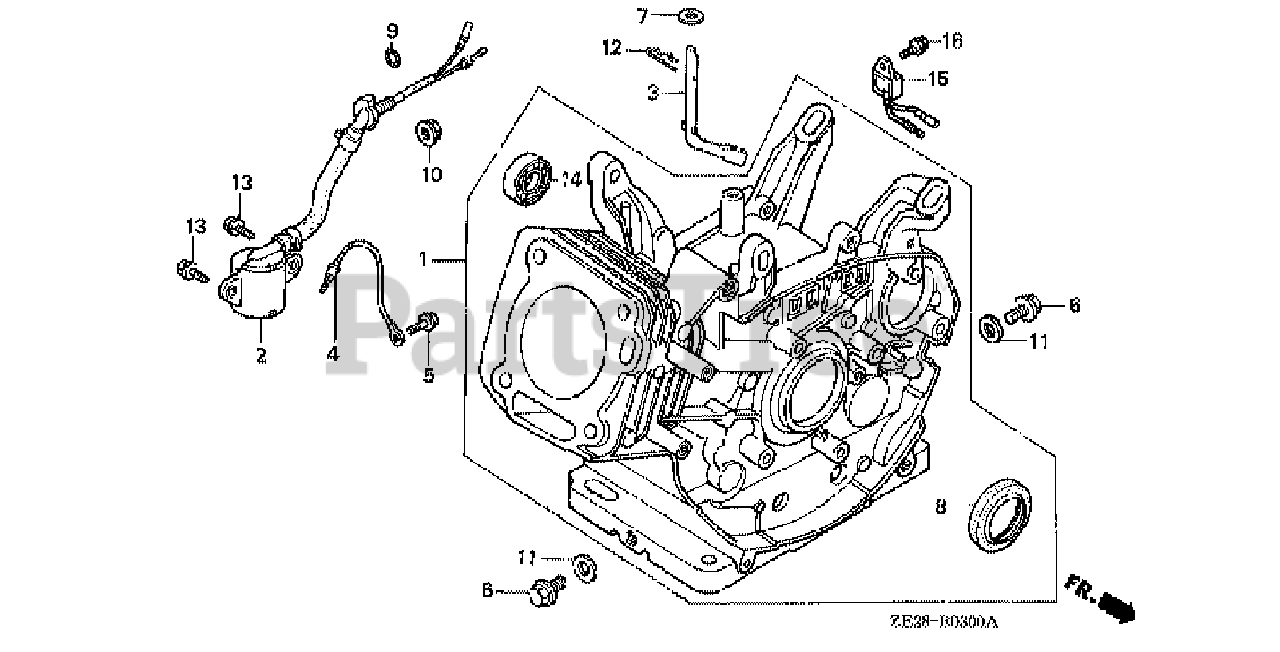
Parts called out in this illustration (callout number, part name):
1	CYLINDER ASSY. (BALANCER+OIL ALERT)
2	SWITCH ASSY., OIL LEVEL
3	SHAFT, GOVERNOR ARM
4	SUB-HARNESS
5	BOLT, FLANGE (6X12) (CT200)
6	BOLT, DRAIN PLUG
7	WASHER (8.2X17X0.8)
8	OIL SEAL (30X46X8)
9	O-RING (13.5X1.5) (ARAI)
10	NUT, FLANGE (10MM)
11	WASHER, DRAIN PLUG (12MM)
12	PIN, LOCK (8MM)
12	PIN, LOCK (10MM)
13	BOLT, FLANGE (6X12)
14	BEARING, RADIAL BALL (6202)
